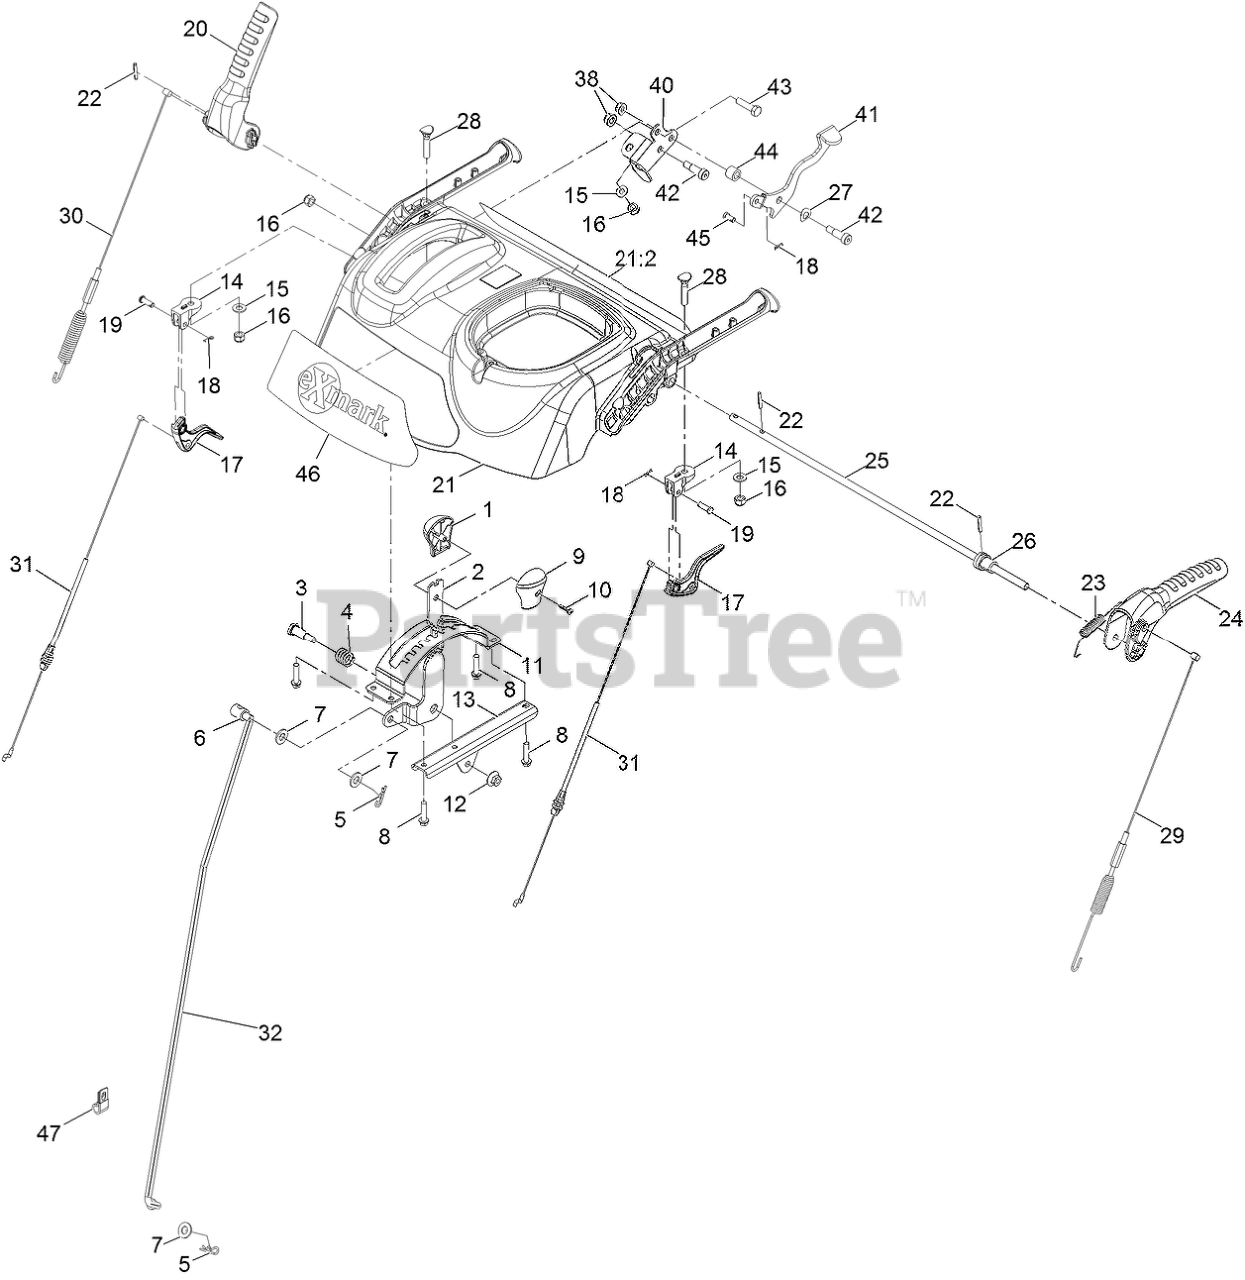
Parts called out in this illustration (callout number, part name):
1	KNOB-SHIFT, RH
2	SELECTOR-SPEED
3	SCREW-SHOULDER
4	SPRING-COMPRESSION
6	TRUNNION-ROD
7	WASHER-FLAT
8	SCREW-PLASTITE
9	KNOB-SHIFT, LH
10	SCREW-PPH
11	GUIDE-SELECTOR, SPEED
13	BRACKET-SELECTOR, SPEED
14	MOUNT-LEVER, CLUTCH
15	WASHER-FLAT
16	NUT-LOCK, NI
17	LEVER-CLUTCH
18	PIN-HAIR
19	PIN-CLEVIS
20	LEVER-AUGER
21	PANEL, CONTROL W/DECAL CE
21:2	DECAL-CONTROL PANEL BACK,
22	PIN-SPRING
23	SPRING-TENSION
24	LEVER-TRACTION
25	ROD-LOCKOUT
26	CAM-LOCKOUT
27	WASHER-SPRING
28	SCREW-HANDLE
29	CABLE-TRACTION
30	CABLE-AUGER
31	CABLE-CLUTCH
32	ROD-SHIFT
38	NUT-HF, NI
40	BRACKET-LEVER, BROOM ANGL
41	LEVER-THUMB, BROOM ANGLE
42	SCREW-SHOULDER, HSH
43	SCREW-HH
44	TUBE-SPACER
45	PIN-CLEVIS
46	DECAL-EXMARK LOGO
47	CLIP-LOOM
